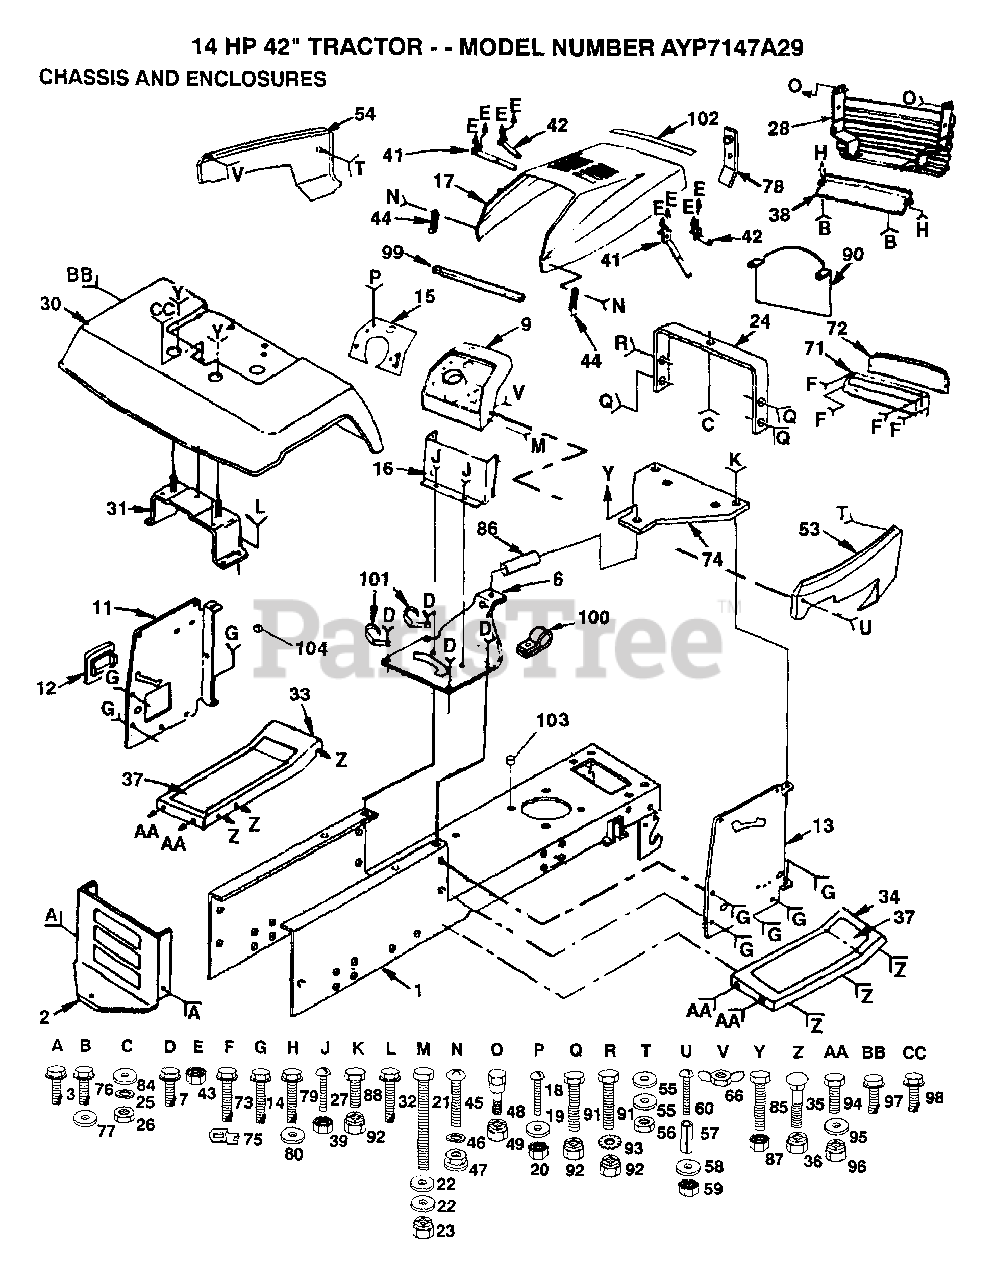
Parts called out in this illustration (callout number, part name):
1	CHASSIS WELDMENT
3	SCREW
7	SCREW LT
11	DASH PANEL LH
12	COVER ACCESS
14	SCREW
18	SCREW
19	WASHER
22	WASHER
24	SUPPORT ASS'Y
25	LOCKWASHER
27	SCREW
30	FENDER
32	SCREW
35	BOLT
37	FOOTREST PAD
43	NUT
44	HOOD LATCH T
45	SCREW
46	LOCKWASHER
47	WELDNUT
55	WASHER PM
57	SPACER LT
58	WASHER
60	SCREW
72	LENS LT
75	"""J"" FASTENER LT"
76	SCREW
77	WASHER
79	SCREW HEX CRT
80	WASHER
82	SCREW
84	WASHER PM
85	BOLT
86	SPACER
90	BAFFLE HOOD VERT
93	LOCKWASHER
95	WASHER
97	SCREW LT
98	SCREW
99	FOAM-STRIP LT
100	CLIP T
101	CLIP T
103	SNAP BUSHING T
